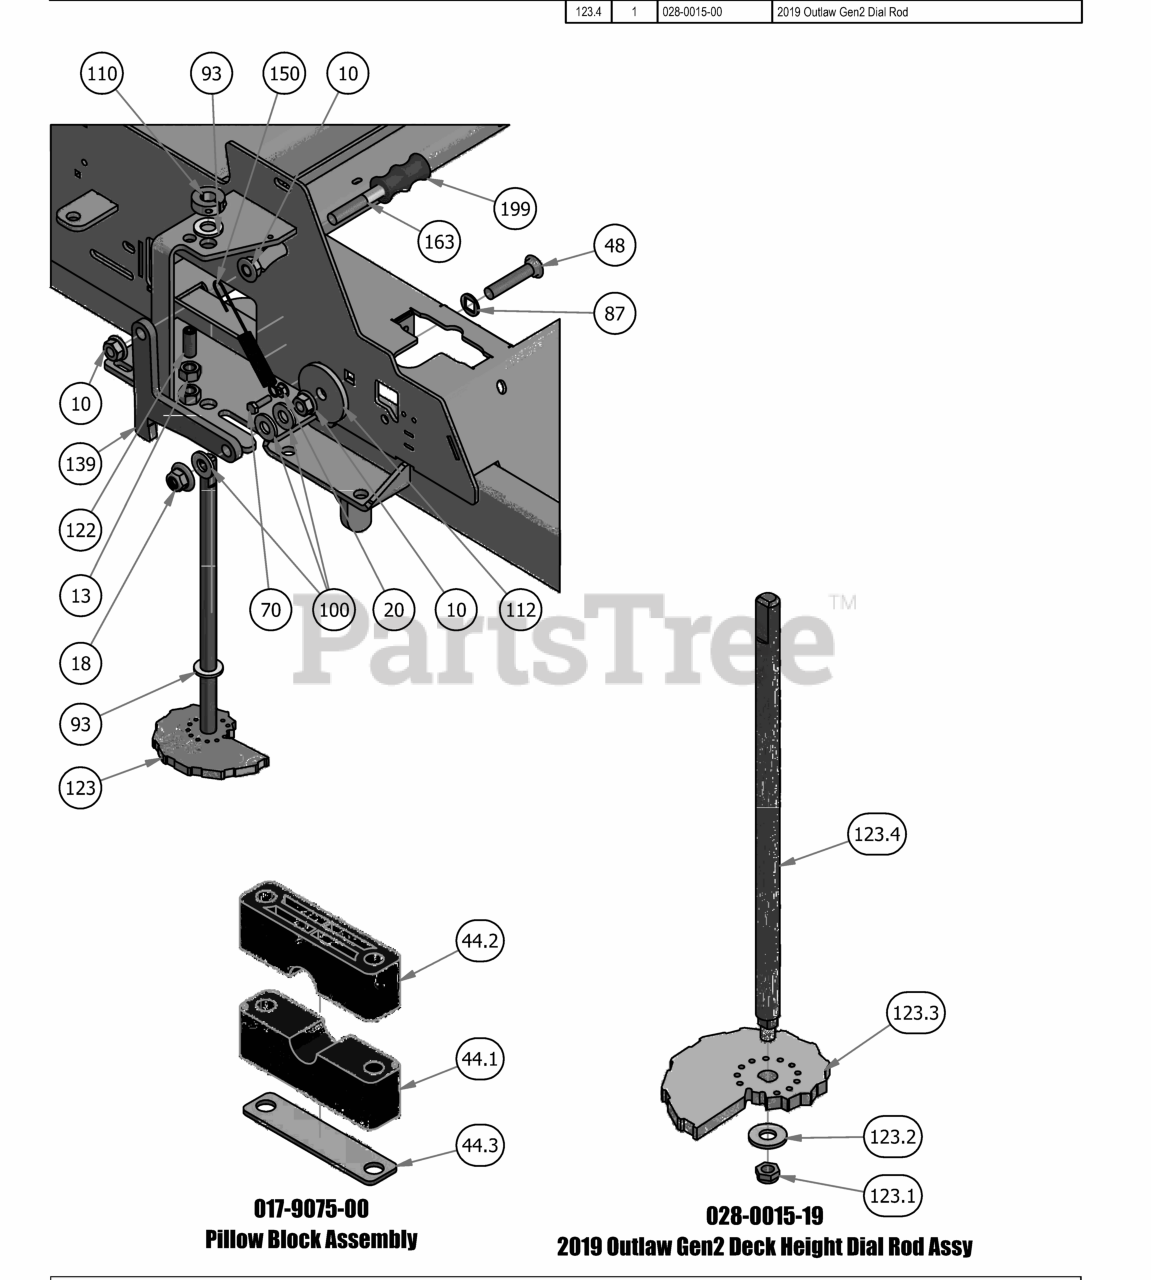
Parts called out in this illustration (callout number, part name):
10	1/2" Flange Nut
13	1/2" Hex Nut
18	1/2-13 Nylon Flange Nut
20	1/4-20 Hex Flange Nuts Zinc w/Serrations
44.1	Two Piece Pillow Block (Male)
44.2	Two Piece Pillow Block (Female)
44.3	Two Piece Pillow Block Strap
48	1/2 x 2-1/2 Carriage Bolt
70	1/4-20 x 1-1/4 GR 5 Hex Bolt
87	.517 Square Hole Round Washer
93	.630 ID Plastic Washer
100	.505 Nylon Spacer
110	5/8" Split Collar
112	MZ Deck Idler Spacer
122	Dial Rod Plunger
123	2019 Outlaw Gen2 Deck Height Dial Rod Assy
123.1	3/8-24 Nylon Insert jam locknut
123.2	3/8" Flat Washer
123.3	2019 Deck Height Cam
123.4	2019 Outlaw Gen2 Dial Rod
139	2019 Outlaw Deck Travel Lock
150	Brake Spring
163	Seat Braket Pin
199	Travel Lock Rubber Grip
